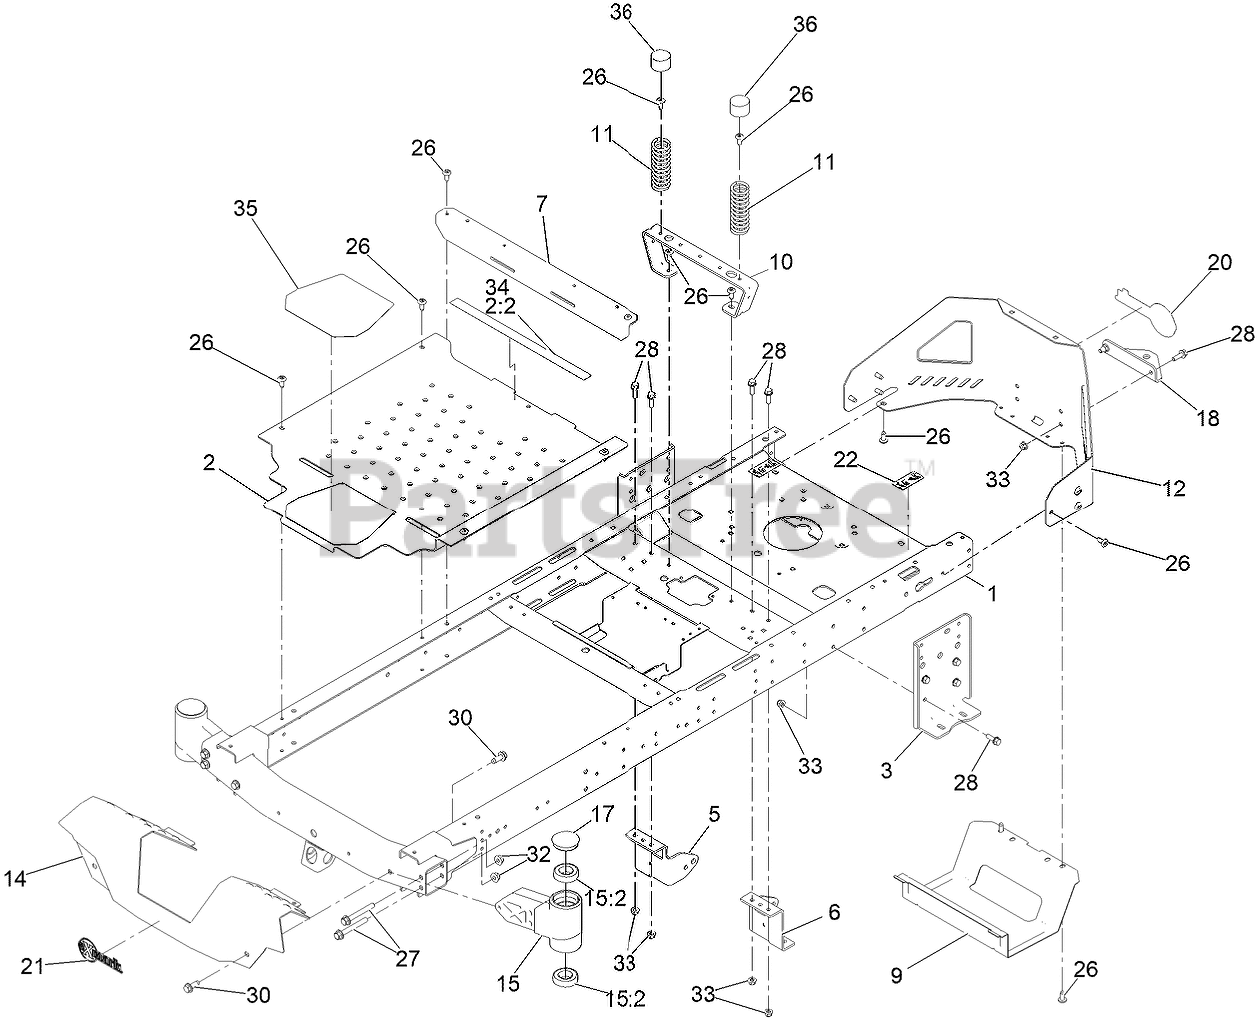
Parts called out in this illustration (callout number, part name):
1	FRAME ASM - RIVETED/WELDED
2	Pan-Floor ASM
2:2	DECAL-WARNING
3	PLATE-MOUNT, HYDRO
5	MOUNT-HYDRO, FRONT (RIGHT
6	Mount-Hydro, Front (Left)
7	BRACE-CROSS
9	GUARD-MUFFLER
10	SUPPORT-SEAT
11	SPRING-COMPRESSION
12	GUARD-ENGINE
15	AXLE-STUB
15:2	BEARING-BALL
17	Cap-Grease
18	BRACKET-HITCH
20	DECAL-EXMARK LOGO
21	DECAL-EXMARK LOGO
22	DECAL-BYPASS
27	SCREW-HHF
28	SCREW-HHF
30	SCREW-HWH
32	NUT-HF, NI
33	NUT-HF, NI
34	DECAL-WARNING
35	TREAD-STEP
36	CAP-PROTECTOR
